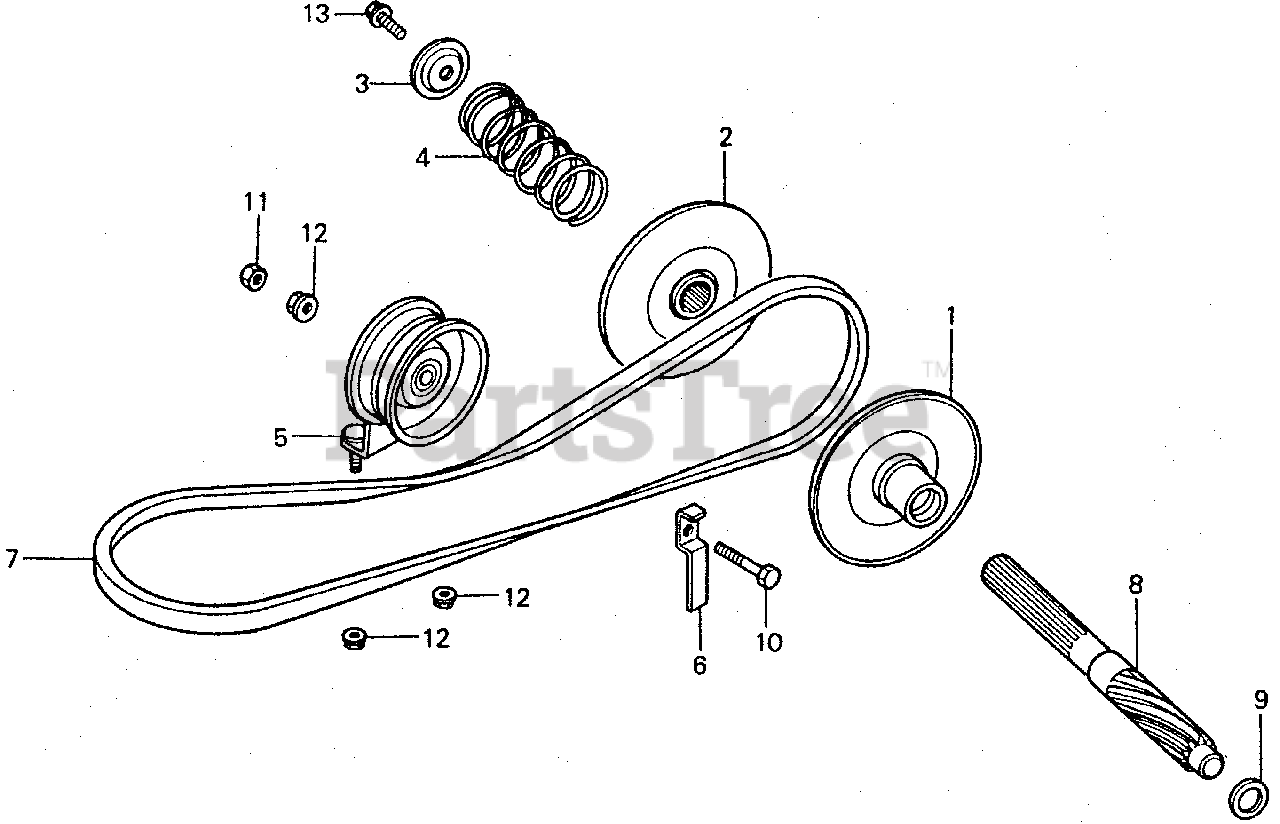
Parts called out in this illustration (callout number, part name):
1	FACE, DRIVEN
2	FACE, MOVABLE DRIVEN
3	SEAT, SPRING (NOT AVAILABLE)
4	SPRING, DRIVEN FACE (NOT AVAILABLE)
5	ROLLER, GUIDE
6	GUIDE, BELT (NOT AVAILABLE)
7	V-BELT, DRIVE
8	GEAR, DRIVE
9	WASHER (8MM) (NOT AVAILABLE)
10	BOLT, HEX. (6X28)
11	NUT, HEX. (6MM)
12	NUT, FLANGE (6MM)
13	BOLT, FLANGE (6X12) Use up to Engine SN 1543277.
